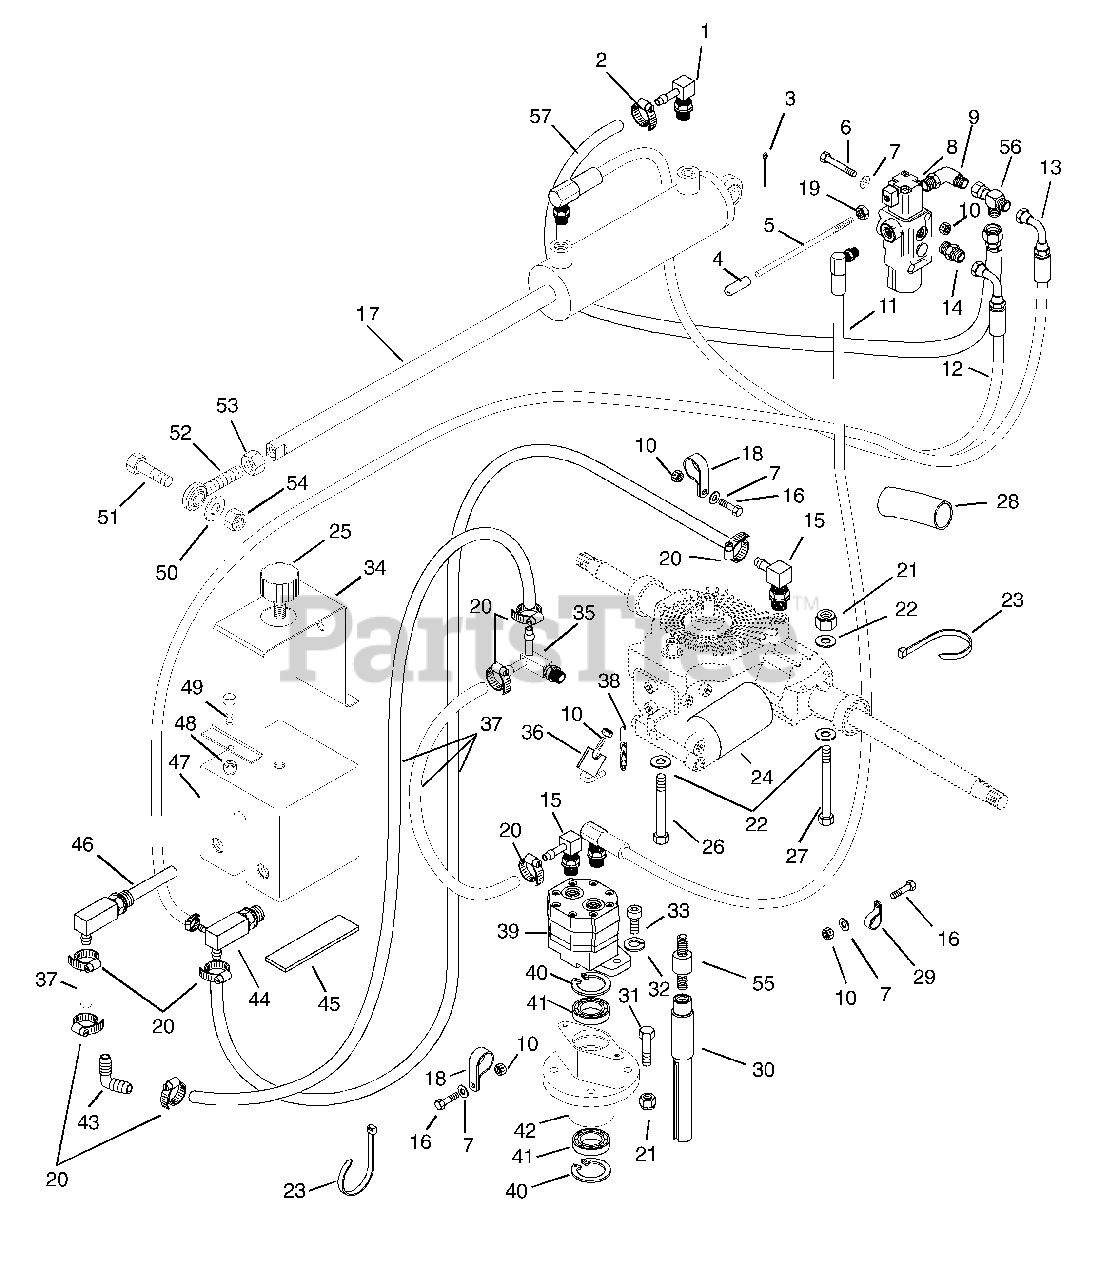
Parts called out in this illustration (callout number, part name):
1	Fitting-Adapter 90 Elbow
2	Clamp-Hose SAE F 06
3	Pin-Cotter .12 x 1.25
4	Grip-PTO Lever
5	Rod-Hydraulic Lift
6	Bolt-Hex .25-20 x 3.00
7	Washer-Flat-Steel .281 x .62 x .065
8	Valve-Hydraulic
9	Fitting-Adapter (TF5515-6-8)
10	Nut-Locking-Center .25-20
11	Assembly-Hydraulic Hose
12	Assembly-Pressure Hose
13	Assembly-Hydraulic Hose
14	Adapter-Pipe .56-18 "O" Ring to .56-18 M37
15	Fitting
16	Bolt-Hex .25-20 x .75 Grade 5
17	Cylinder
18	Clamp, Steel 1.0
19	Nut-Jam M10-1.5
20	Clamp .88 Dia. Hose
21	Nut-Locking-Center .375-16
22	Washer-Flat-Steel .406 X .812 X .065
23	Tie Wrap-Black
24	Filter-Oil
25	Cap-Filter
26	Bolt-Hex .38-16 x 3.25 Grade 5
27	Bolt-Hex .38-16 x 4.00 Grade 5
28	Sleeve-Protective
29	Clamp-Cushioned Steel
31	Bolt-Hex .38-16 x 1.50 Grade 5
32	Washer-Locking .38 x .094
33	Screw-Cap 38-16 x .75 Socket Head
34	Strap-Tank
35	Fitting-Pipe .875-14
36	Weldment Lever
37	Hose
38	Spring-Tension .061 x .50 x 3.5
39	Pump-Hydraulic
40	Ring-Retaining-Internal 2.210 x .062
41	Bearing-Ball 1.0 x 2.0 x .56
43	Elbow-Barbed .63 x .63
44	Fitting with O-Ring 88-14 x .268
45	Pad, Gas Tank
46	Fitting-Filter
47	Tank Hydraulic
48	Nut-Locking-Center .31-18
49	Bolt-Hex .31-18 x .75 Grade 5
50	Washer-Flat-Steel .50 x 1.25 x .083
51	Bolt-Hex .50-13 x 1.50 Grade 5
52	Assembly-Rod End (Right Hand)
53	Nut-Jam .50-20 Grade 2
54	Nut-Locking-Center .50-13
55	Coupler, Drive
56	Fitting-Adapter Tee (6602-6-6-6)
57	Hose 3/8" x 48" with Fitting
